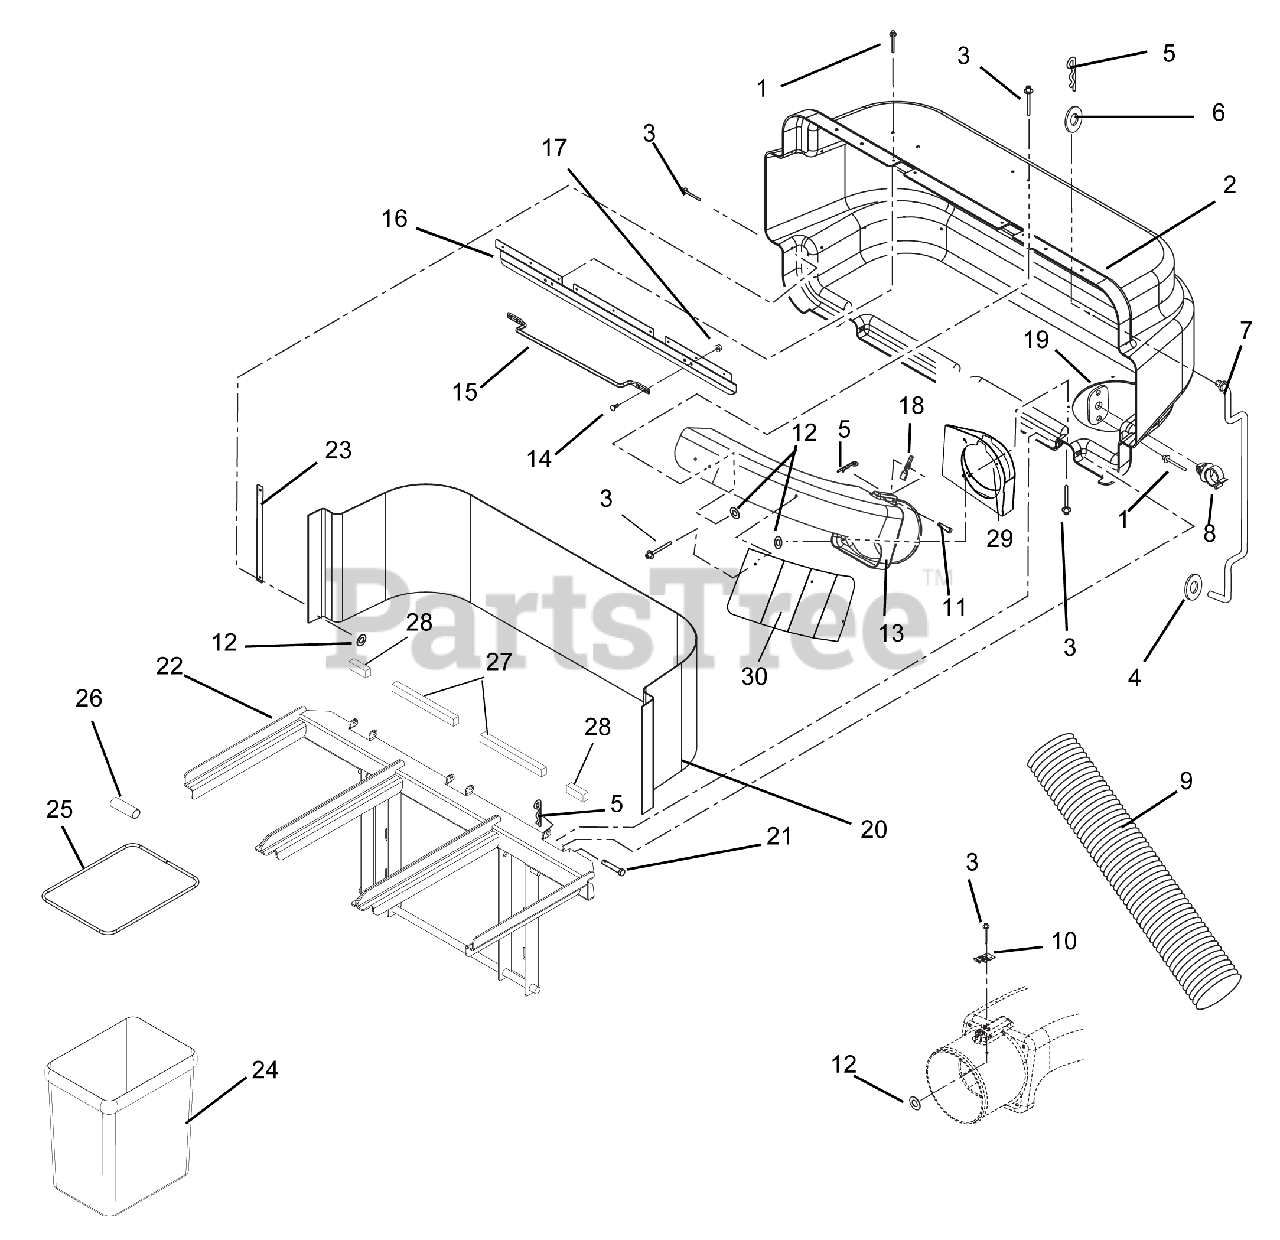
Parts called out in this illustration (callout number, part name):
1	RVT-POP .187X.402 DOME ST
2	ASM, HD BAGGER COVER
3	RVT-POP.187X.527 DOME ST
4	RETAINER, .38 PUSH-ON
5	PIN-HAIR, ENDRIES #25 YWZC
6	@WSHR-FL-STL.406X.812X.065 YWZ
7	PROP-ROD, BAGGER
8	CLIP-.38
9	HOSE,7X63 GOODYEAR 586-429-171
10	THUMB LATCH
11	PIN-CLEV .309 X 1.625 YWZC
12	@WSHR-FL-STL.219X.50X.049 YWZC
13	BOOT,UPPER
14	@BLT-RDHDSQNK .25-20X.75 G5YZ
15	BAGGER HANDLE
16	LATCH, BAGGER (ZOOM)
17	@NUT-LK-TOP-FLG .25-20 YWZC
18	INDICATOR, FLOW
19	PLATE, ROD CLIP
20	SCREEN, BAGGER
21	PIN-CLEV .371X3.25 YWZC
22	WMT, XL BAGGER FRAME
23	STRAP,COVER
24	BAG, MESH XL BAGGER
25	FRAME, ZOOM BAG
26	HOSE, .38 X.50 X 3.00 VINYL
27	BLOCK, 10.5 IN FOAM GRASS
28	BLOCK, 4 IN FOAM GRASS
29	WMT, HOSE INSERT SUPPORT
30	DEFLECTOR, HD BAGGER
